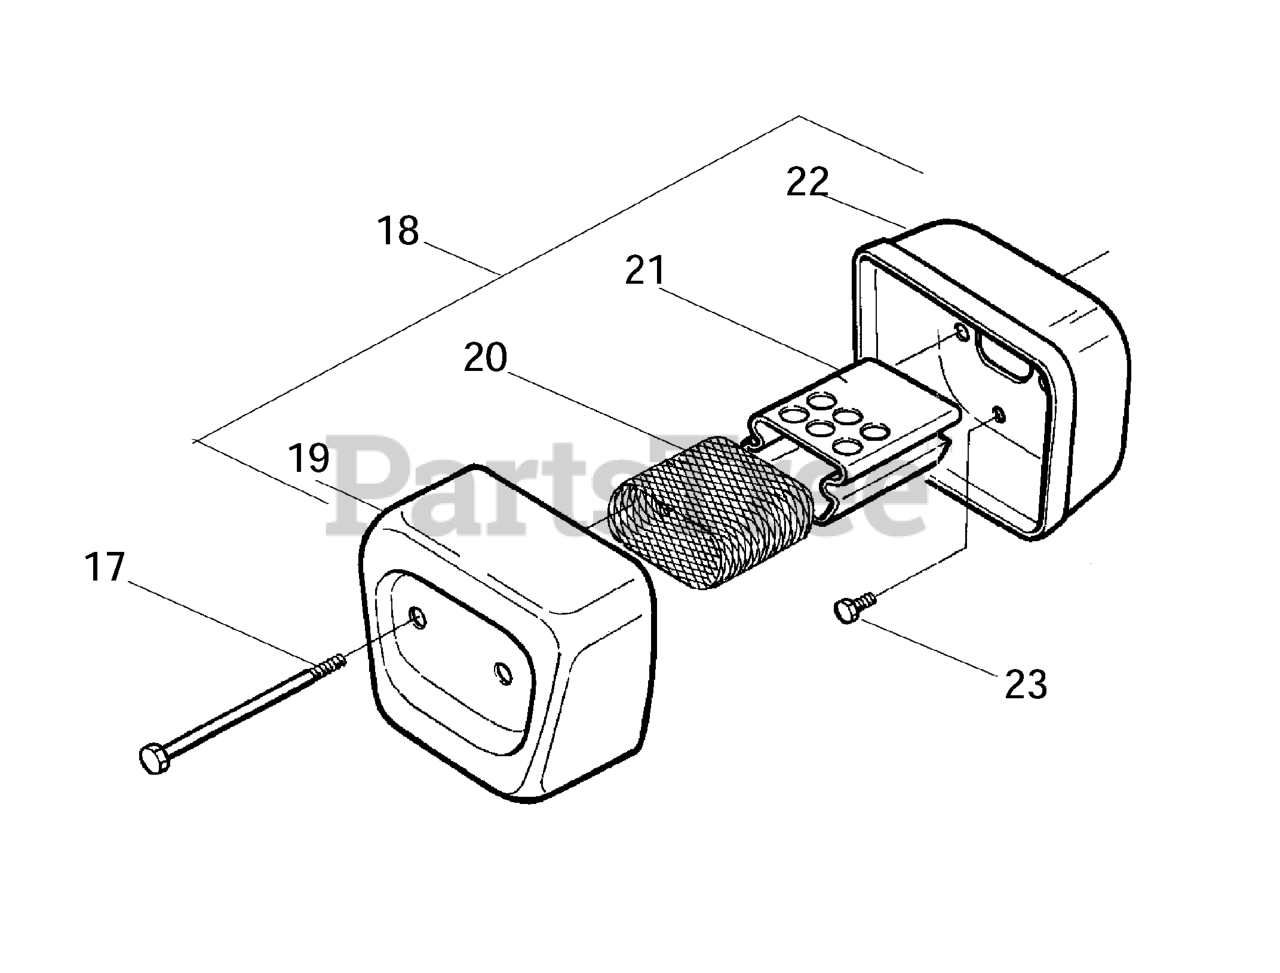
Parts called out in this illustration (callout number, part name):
18	MUFFLER KIT
19	SILENCER COVER
20	SPARK ARRESTOR 36/41
21	FLAME PROTECTOR
22	SILENCER BODY
23	BOLT-MUFFLER(SUPPORT)
